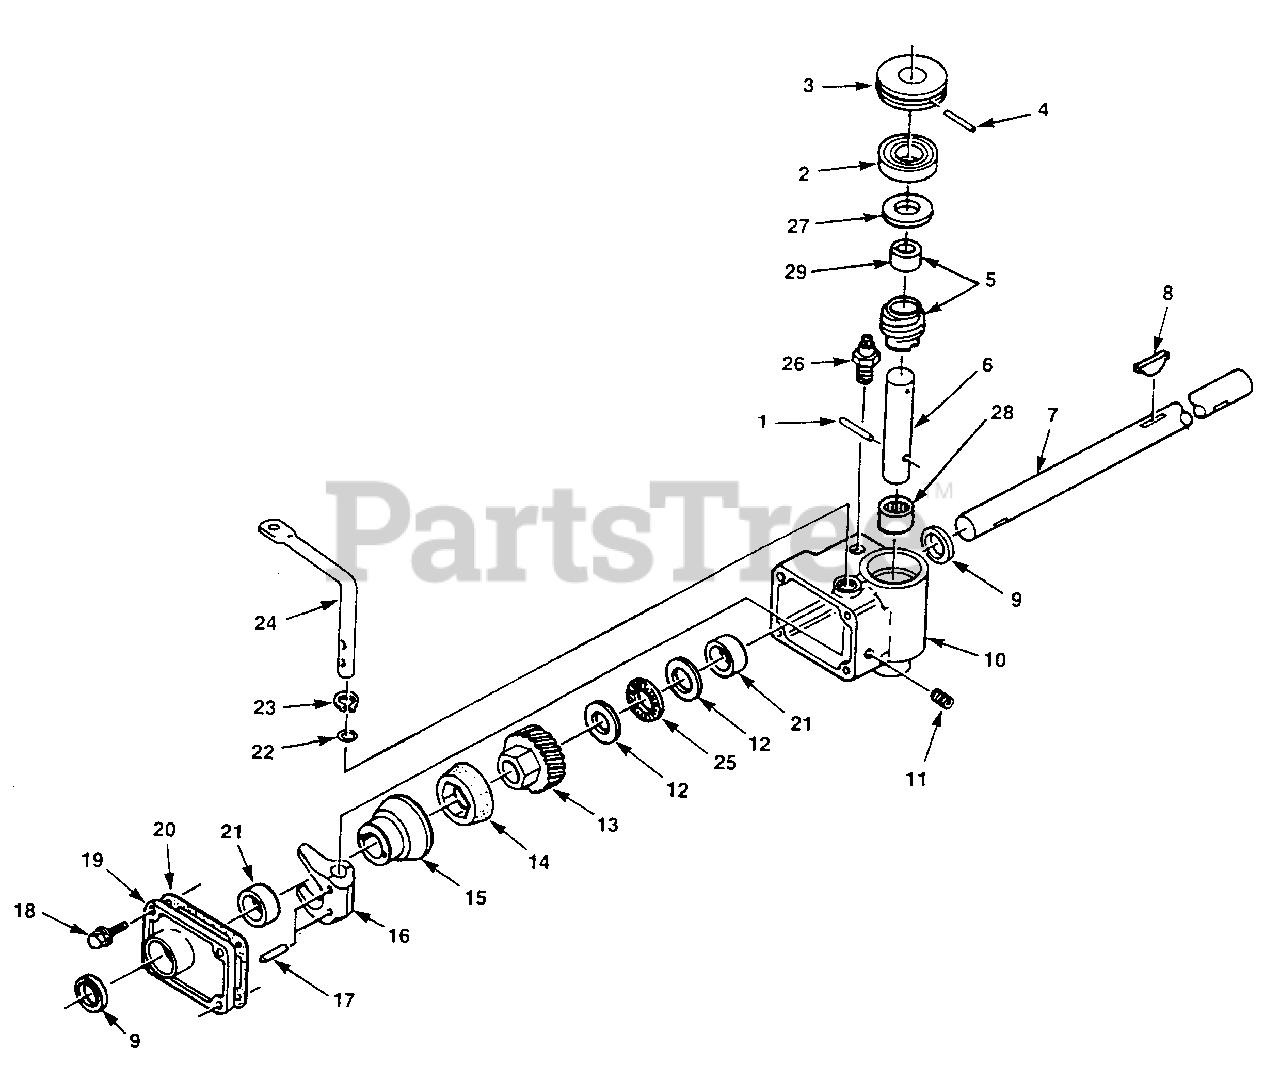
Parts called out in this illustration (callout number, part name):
3	PULLEY
5	WORM & SPACER
6	SHAFT- Worm
7	SHAFT- Drive
10	GEAR REDUCER HOUSING ASSY.
12	RACE- Bearing
13	GEAR- Helical
14	CONE- Friction
15	DRUM- Clutch
16	FORK- Shift
18	SCREW- Sems hd. 1/4-20 x 7/8
19	COVER- Gearbox
20	GASKET
21	BUSHING- Sleeve
24	LEVER- Shift
25	BEARING- Thrust
28	BEARING- Needle
